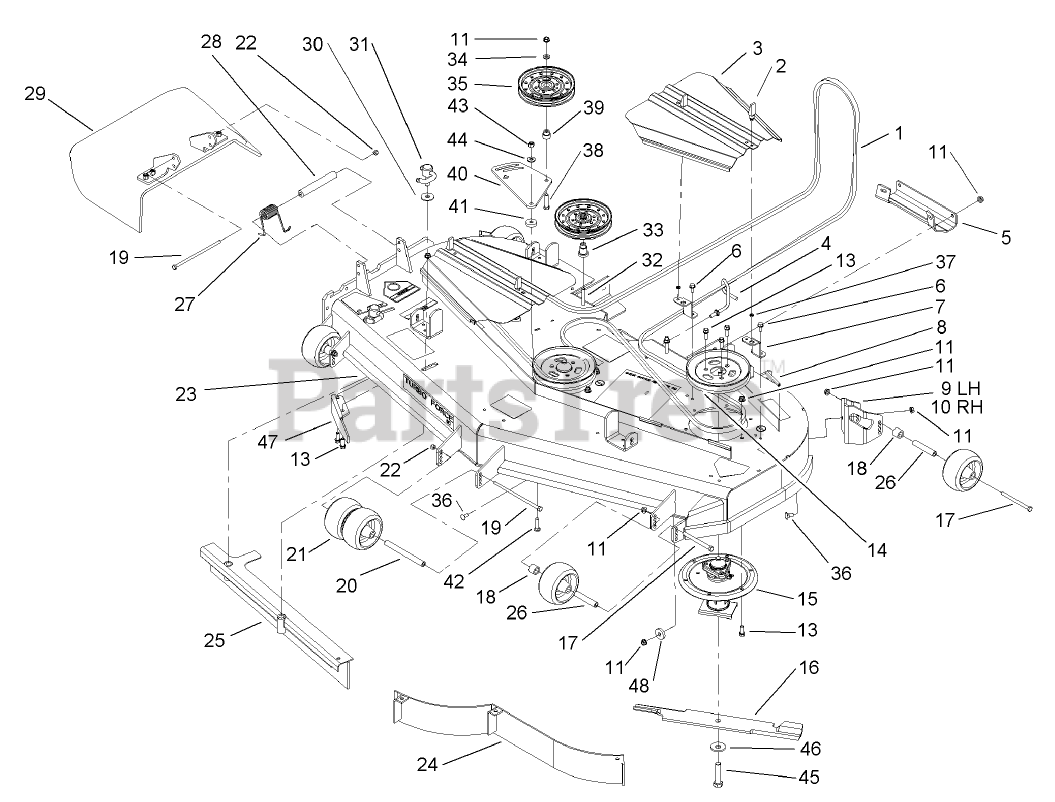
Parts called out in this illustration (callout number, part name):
2	LATCH-SWELL
3	Cover-Belt
4	GUIDE-BELT
5	Plate-Skid
6	SCREW-HWHTF
7	Bracket-Cover
8	STRIP-SEAL
9	MOUNT-WHEEL, LH
10	MOUNT-WHEEL, RH
11	NUT-HHF, WHIZ
13	SCREW-TAPTITE
14	Pulley
15	Spindle ASM
16	Blade-Rotary, High Flow
17	SCREW-HH
18	TUBE-SPACER
19	SCREW-HH
20	SPACER-WHEEL
21	ROLLER-SCALP, ANTI
22	NUT-LOCK, NI
23	Deck Decal ASM
26	TUBE-SPANNER
27	SPRING-TORSION
28	SPACER
29	Rubber Deflector ASM
30	WASHER-PLASTIC
31	Lever ASM
32	SCREW-HH
33	MOUNT-PULLEY
34	WASHER-FLAT
35	Idler-Flat
36	SCREW-CARR
37	WASHER
38	SCREW-HH
39	BUSHING-IDLER
40	Plate-Idler
41	Spacer
42	SCREW-CARR
43	NUT-LOCK, NI
44	WASHER-BELLEVILLE
45	Screw-Cap
46	Washer-Blade Bolt, Heavy
47	BAFFLE-DISCHARGE
48	WASHER
